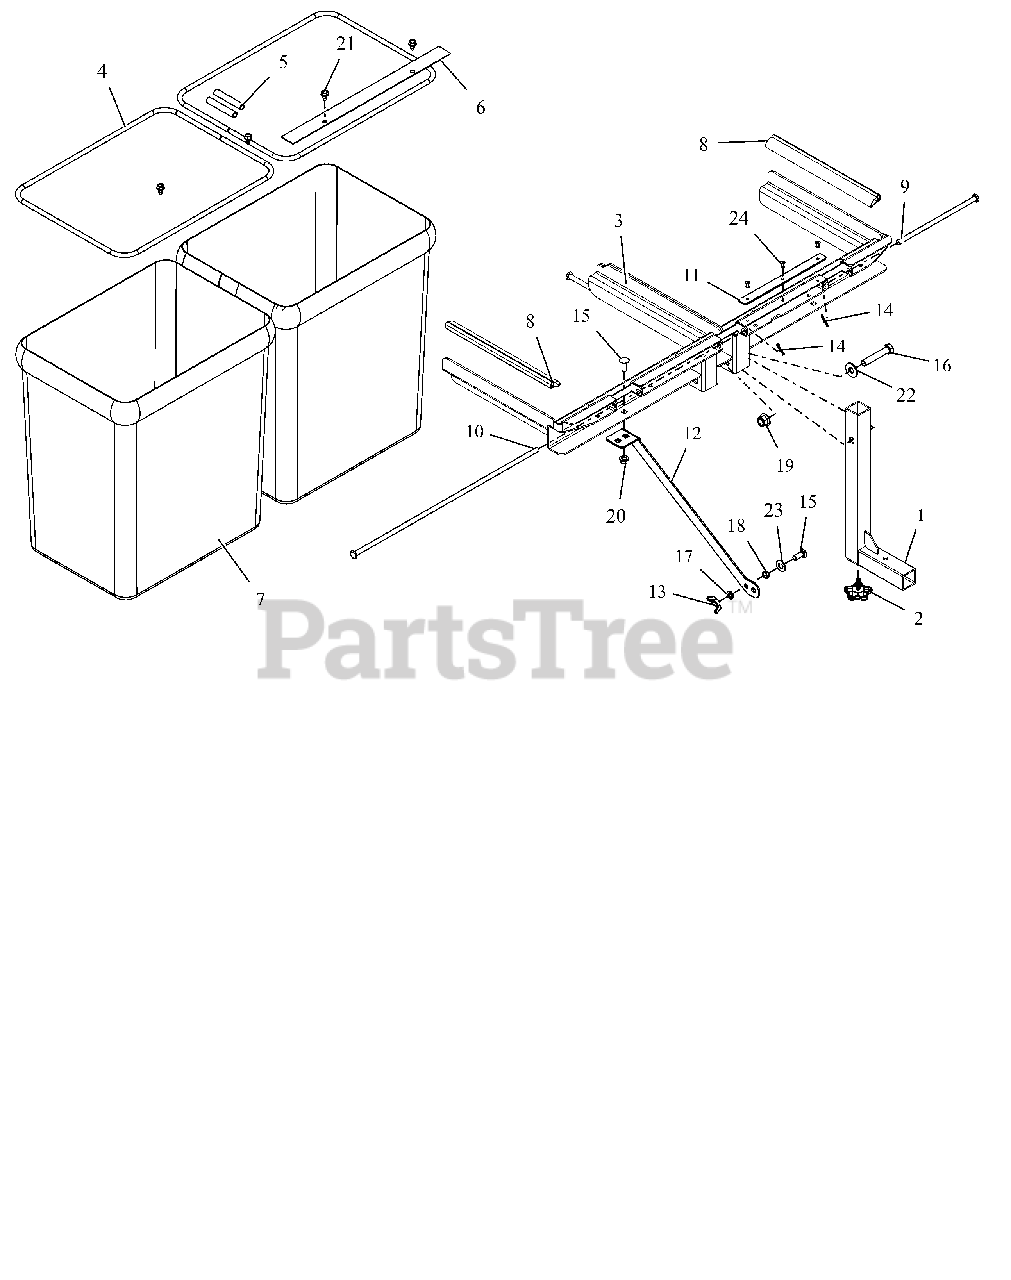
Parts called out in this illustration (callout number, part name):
1	WLDMT, BAGGER MOUNT POST(2BKT)
2	KNOB, WING STUDDED
3	ASS'Y, BAGGER FRAME UPPER
4	FRAME, ZOOM BAG
5	HOSE, .38 X.50 X 3.00 VINYL
6	BRKT-BAGGER OVERLAP
7	BAG, MESH ZOOM
8	SEAL, BULK
9	PIN, BAGGER HINGE (L)
10	PIN, BAGGER HINGE (R)
11	SEAL, HINGE
12	BRACKET, BAGGER SUPPORT (EXT)
13	NUT-WING .375-16 ZCC
14	PIN-HAIR, ENDRIES #25 YWZC
15	@BLT-RDHDSHSQNK.38-16X1.0 G5YZ
16	BLT-HEX .50-13X2.75 YZ GR8
17	WSHR,LK-REG .375X.094 ZCC
18	NUT-HEX-JAM .375-16 YWZC
19	@NUT-LK-NYL-FLG .50-13 YWZC
20	@NUT-LK-TOP-FLG .38-16 YWZC
21	@SCR-TAP .31-18X.50 HWH TR YWZ
22	WSHR-FL-STL .531X1.250X.10 YWZ
23	WSHR-FL-STL .505X1.00X.062YWZC
24	RVT-POP.187X.527 DOME ST
